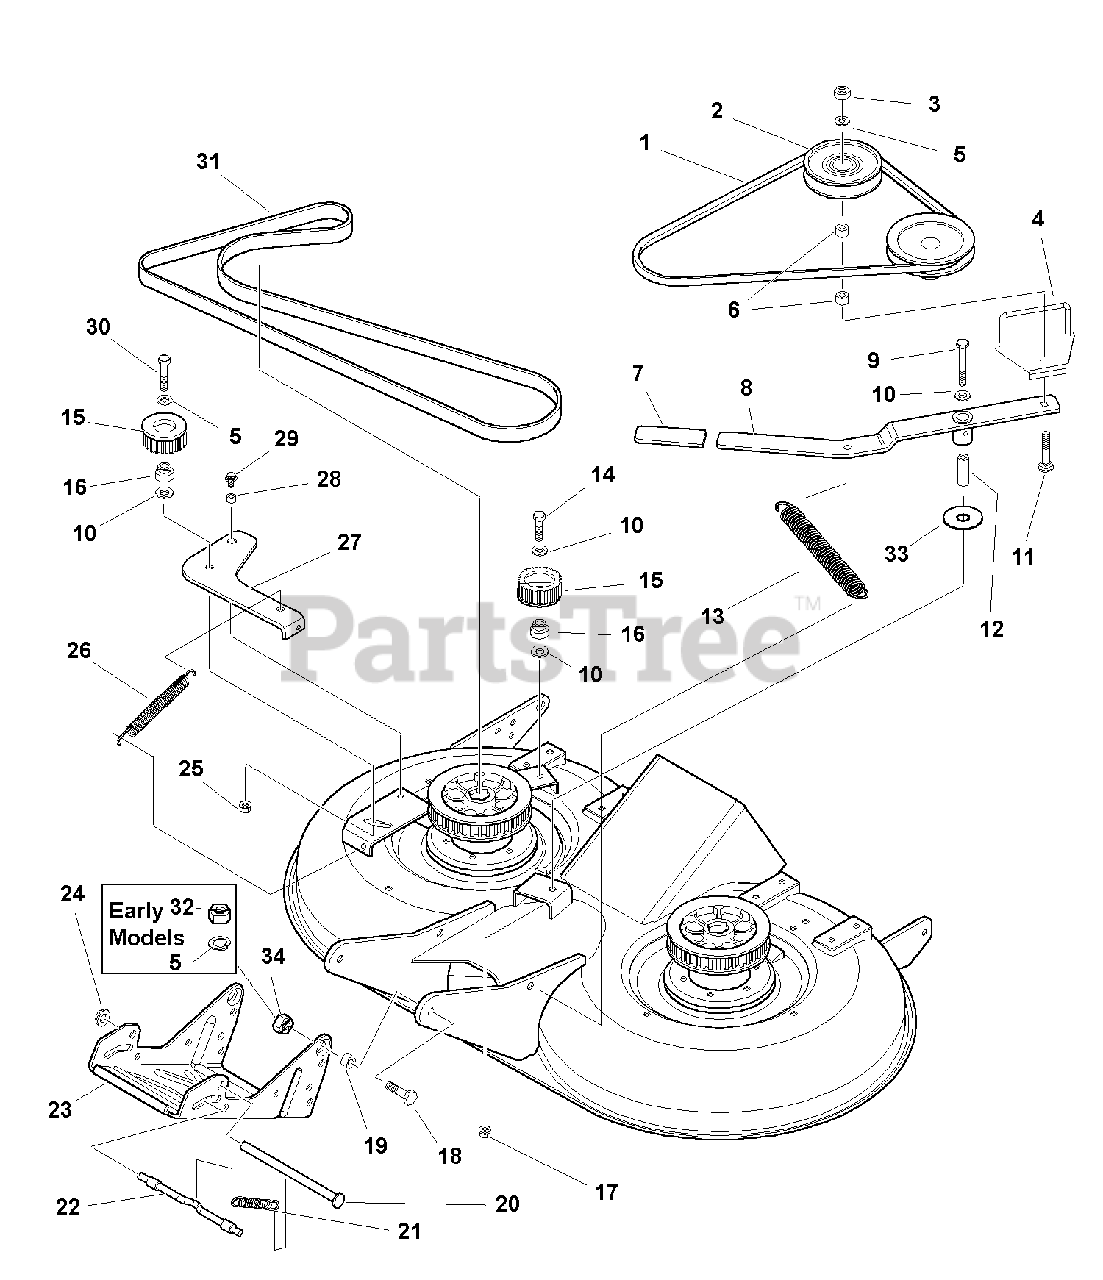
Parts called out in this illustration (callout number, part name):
1	V-BELT, Mower Drive, PTO
3	NUT, Hex Lock ESNA Light, 3/8-16
5	WASHER, 3/8
7	GRIP, Black Vinyl
8	ARM ASSEMBLY, Idler w/Bushings & Lube
9	CAPSCREW, Hex Head, 3/8-16 x 2-3/4 G8
10	WASHER, 3/8
11	CARRIAGE BOLT, 3/8-16 x 2-1/2
13	SPRING, Extension
14	CAPSCREW, Hex Head, 3/8-16 x 1-3/4
15	PULLEY, Idler 22 Teeth
17	NUT, Hex Flange Whizlock, 3/8-16
18	CAPSCREW, Hex Head, 3/8-16 x 1-1/2
20	ROD, Mower Hitch
21	SPRING, Extension
23	HITCH, Mower
24	NUT, Push On
25	WASHER & LOCK NUT ASSEMBLY, 3/8-16
26	SPRING, Extension
27	ARM, Idler
29	CAPSCREW, Hex Washer Head, Taptite, 5/16-18 x 1/2
30	CAPSCREW, Hex Head, 3/8-16 x 2
31	BELT, Timing, Arbor Drive
32	NUT, Hex Lock ESNA Heavy, 3/8-16
33	WASHER
34	NUT, Hex Lock Alum Insert, 3/8-16 (SN 2000 and above)
